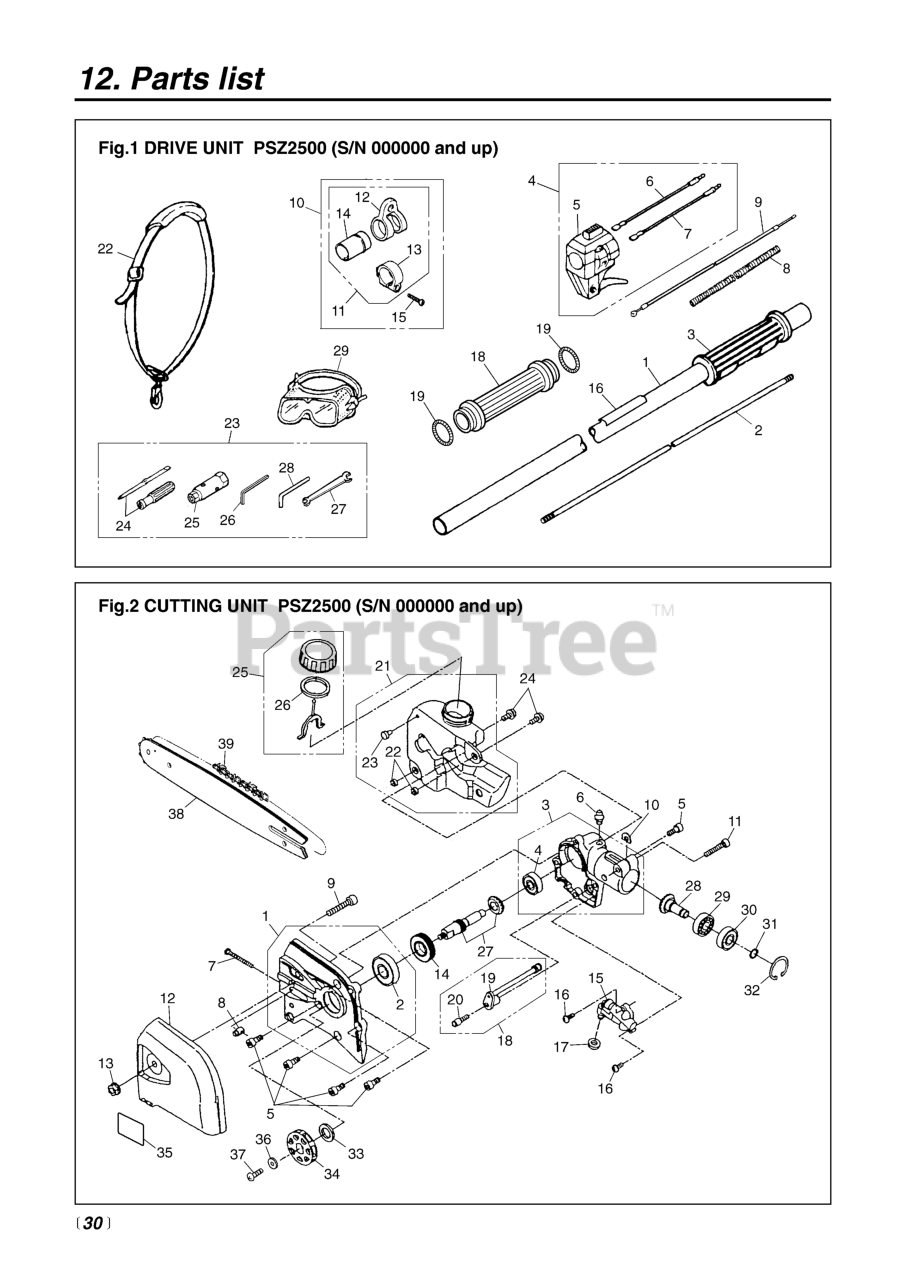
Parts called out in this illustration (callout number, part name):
1	PIPE COMP (REPLACES -12100)
2	SHAFT (RPLS -12212)
3	GRIP
5	LEVER (USE 848-8R2-0313)
6	CORD (A), BLACK
7	CORD (B), RED
8	TUBE (RPLS 4900-72141)
9	CABLE (RPLS 5580-83100)
10	HANGER ASSEMBLY
11	HANGER COMPLETE
12	HANGER
13	CLAMP
14	SLEEVE
15	SCREW, M5 x 25
16	PLATE, NAME
18	GRIP
19	SPRING
22	STRAP ASSY.
24	SCREWDRIVER
25	SOCKET
26	WRENCH (TOOL)
27	SPANNER, 8 X 10 (RPLS 2540- )
28	BAR
29	GOGGLE
A2	BEARING
A3	GEARCASE COMP (RIGHT)
A5	BOLT, M5 x 12
A6	FITTING, GREASE
A7	SCREW
A8	NUT
A9	BOLT, M6 x 30
A10	SHIM
A12	COVER, CHAIN
A13	NUT
A14	GEAR, WORM
A15	PUMP ASSY, OIL
A16	SCREW, M4 x 10
A17	GASKET
A18	PIPE ASSY, OIL
A19	PIPE, OIL
A20	FILTER
A21	TANK ASSY, OIL
A22	COLLAR
A23	VALVE
A24	SCREW, M5 X 12
A25	CAP ASSY, OIL
A26	GASKET, OIL CAP
A27	SHAFT, GEAR
A28	GEAR, BEVEL
A29	BEARING (RPLS T3403-13530)
A31	RING, SNAP (RPLS T3300-13330)
A32	RING, SNAP, M24 x 1.2
A33	COLLAR
A34	SPROCKET
A35	LABEL (PSZ2500)
A36	WASHER
A37	SCREW
A39	12
